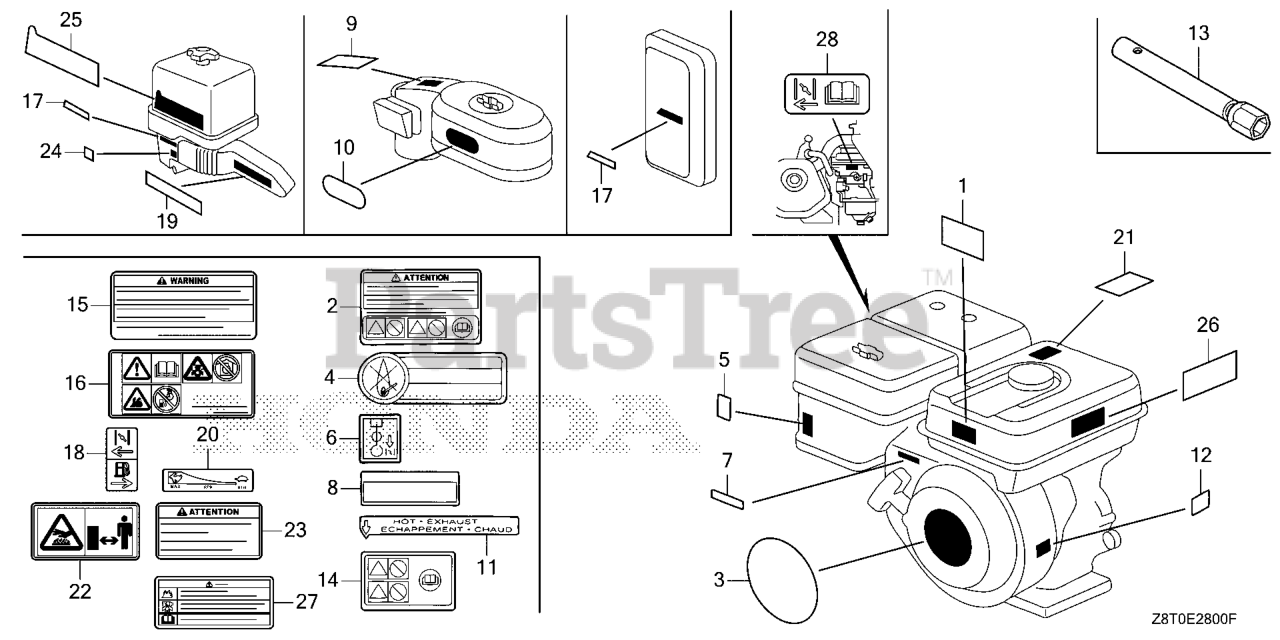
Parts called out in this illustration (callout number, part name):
3	EMBLEM (GX340)
5	MARK, CHOKE
7	MARK, THROTTLE INDICATION
13	WRENCH, SPARK PLUG
15	MARK, OPERATOR CAUTION (FRENCH)(MADE IN THAI)
16	MARK, OPERATOR CAUTION (PICTOGRAPH)
21	MARK, EX. CAUTION (ENGLISH)
22	MARK, EX. CAUTION (PICTOGRAPH)
23	MARK, EX. CAUTION (FRENCH)
26	MARK, OPERATOR CAUTION (ENGLISH)(MADE IN THAI)
27	MARK, OPERATOR CAUTION (CHINESE)
